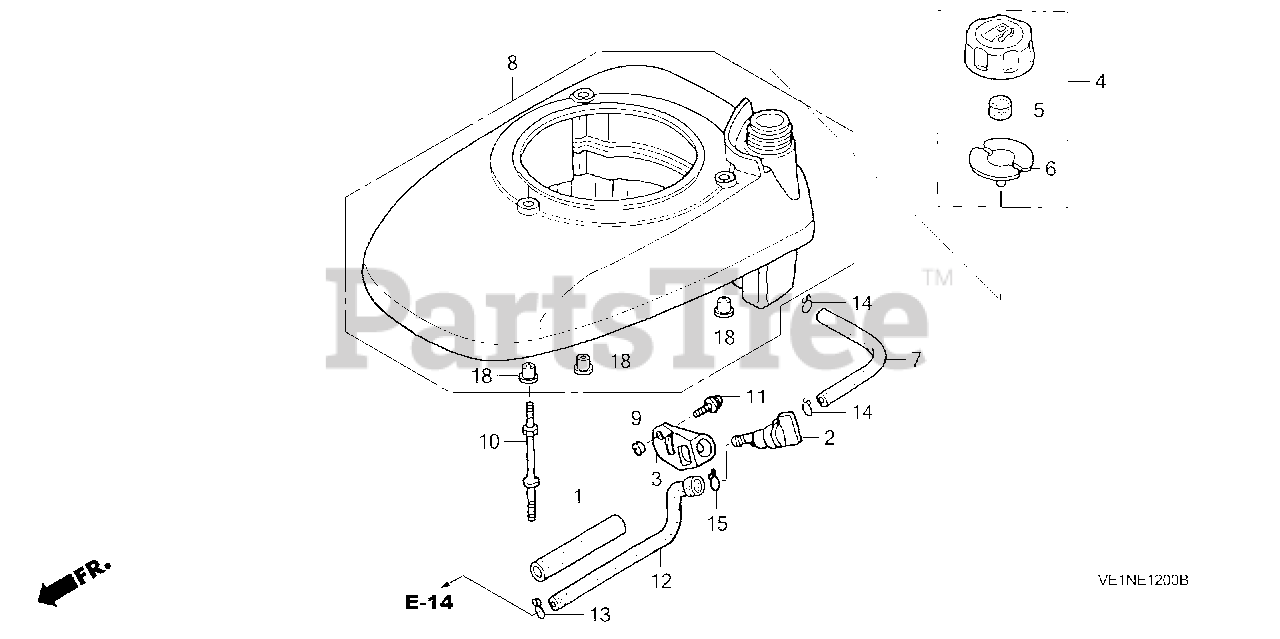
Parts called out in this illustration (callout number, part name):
1	RUBBER, SUPPORTER (107MM)
2	PETCOCK ASSY.
3	BRACKET, PETCOCK
4	CAP ASSY., FUEL TANK
5	SPONGE, FUEL CAP BREATHER
6	GASKET, FUEL CAP
7	BULK HOSE, FUEL (5.5X3000) (5.3X150)
8	COVER, FAN *R280* (POWER RED)
9	COLLAR, FR. TURN SIGNAL
10	BOLT, STUD (H=42.5MM)
11	SCREW-WASHER (5X10)
12	TUBE, FUEL
13	CLIP, TUBE (B8)
14	CLIP, TUBE (B10)
15	CLIP, TUBE (C9)
18	COLLAR, FAN COVER
